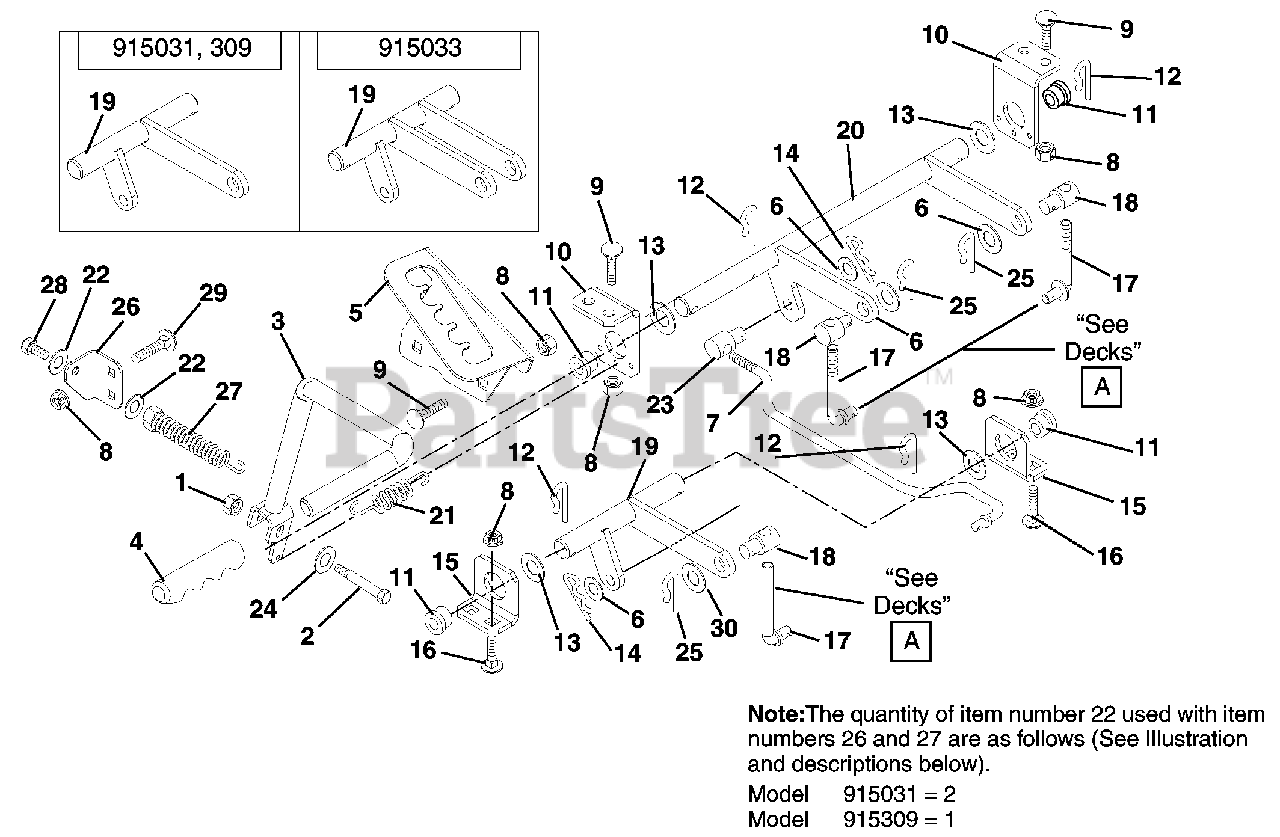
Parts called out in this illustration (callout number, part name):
1	NUT-LK-TOP-FLG .31-18 BLKZC
2	BOLT,SHLDR .38X1.25 .31-18 PLN
3	WLDM'T LIFT HANDLE
5	DETENT PLATE
6	WSHR-FL-STL.511X1.441X.125 YWZ
7	ROD, DECK LIFT
8	NUT-LK-TOP-FLG .38-16 BLKZC
9	BLT-RDHDSQNK .38-16X.75 G5BZ
10	BRACKET-HANGER
11	BSHG-FLG .750X1.000X.625X1.250
12	PIN, SPRING CLIP
13	@WSHR-FL-STL.812X1.50X.135YWZC
14	PIN, HAIR, EXT - #16 YWZC
15	BRACKET-PIVOT
16	BLT-RDHDSQNK .38-16X1.00 G5BZ
17	LINK, LIFT
18	TRUNNION-.50
19	WMT, FRONT LIFT
20	WMT, REAR LIFT
21	SPRING, EXTENSION
22	WSHR,FLT .438X1.00X.160 ZCC
23	PIVOT, ROD
24	WSHR,FLT .438X1.00X.160 ZCC
25	CLIP, SPRING
26	BKT, SPRING ANCHOR
27	SG-TENS .195X1.147X5.50
28	@BLT-HEX .38-16X1.50 GR5 YWZC
29	@BLT-RDHDSQNK .38-16X1.25 BKZC
30	@WSHR-FL-STL.563X1.38X.109YWZC
